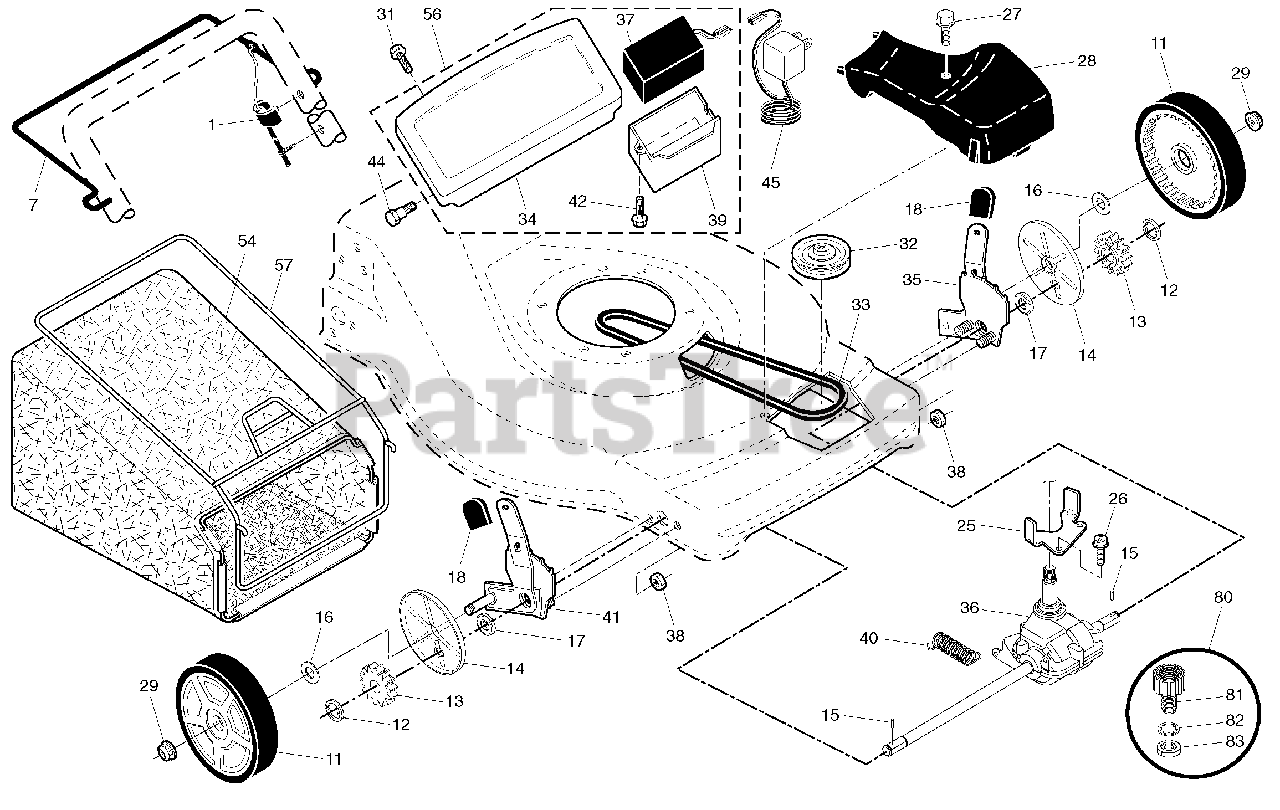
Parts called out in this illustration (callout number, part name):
1	Drive Control Assembly
7	Bar, Drive Control
11	Wheel & Tire Assembly, Front
12	E-Ring
13	Pinion
14	Dust Cover
15	Pawl, Drive
16	Washer, Flat 3/8
17	Bearing, Wheel Adjuster
18	Selector Knob
26	Screw, Hi-Lo Thread
27	Screw, Pan Head, Self-Tapping #10-24 x 2-3/4
28	Drive Cover
29	Locknut, Hex
31	Screw, Trimplate
32	Pulley, Drive
33	V-Belt
34	Trimplate
35	Kit, Wheel Adjuster, LH
36	Gear Case Assembly, Complete
37	Battery
38	Locknut 1/4-20
39	Battery Box
40	Spring
41	Kit, Wheel Adjuster, RH
42	Screw, Battery Box
44	Screw, Trimplate
45	Charger, Battery
54	Grassbag Assembly
56	Trimplate, Battery Box and Battery Assembly
57	Frame, Grassbag
80	Water Washout Assembly
81	Fitting, Hose, Water Washout
82	Washer, Lock, Internal Tooth
83	Locknut, Hex, with O-Ring
